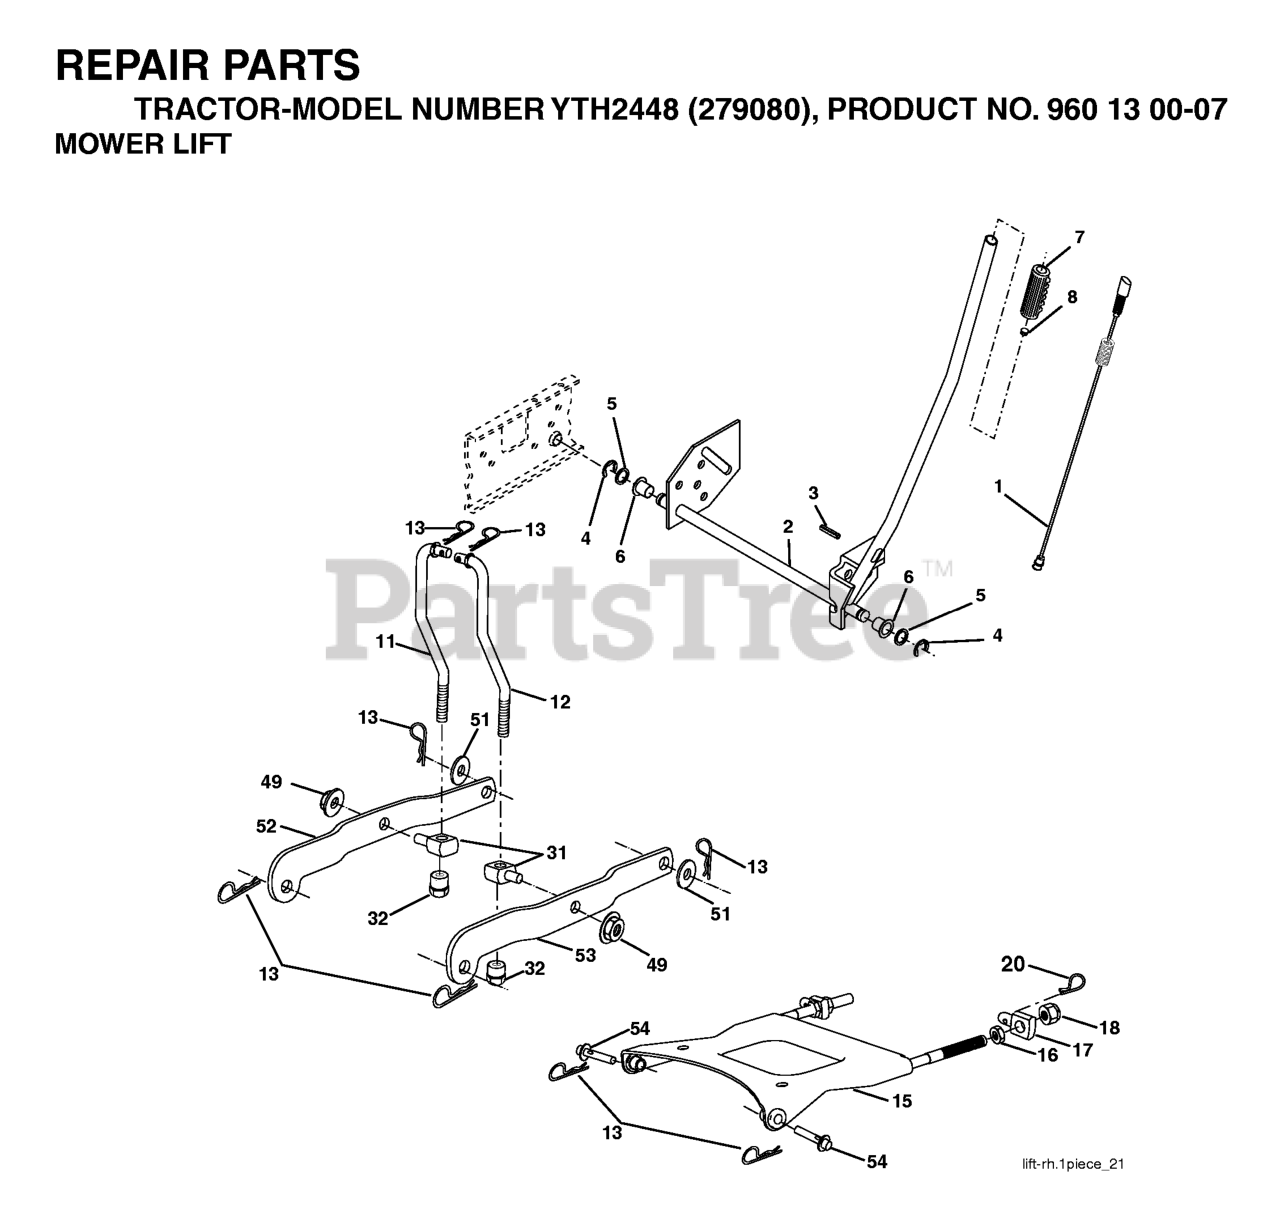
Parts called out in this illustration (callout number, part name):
1	WIRE ASM INNER W/ PLUNGER LT
2	SHAFT ASM R HANDLE
3	PIN GROOVE.
4	RETAINING RING LT
6	BEARING.NYLON
7	GRIP HANDLE
8	PLUNGER BUT KIT
11	LIFT LINK LH
12	LIFT LINK RH
13	RETAINER-SPRNG RB
15	PLATE ASM SUSP FRONT
16	NUT.HEX.JAM.1/2-13
18	NUT.LK.W/WSH.1/2.
20	SPRING RETAINER
32	NUT, LIFT LINK 7/16-20
49	NUT
51	Washer 1 17/32 X 7/8 X 16 Ga
52	ARM SUSP. REAR LH
53	ARM SUSP REAR RH
54	PIN.FLANGE
